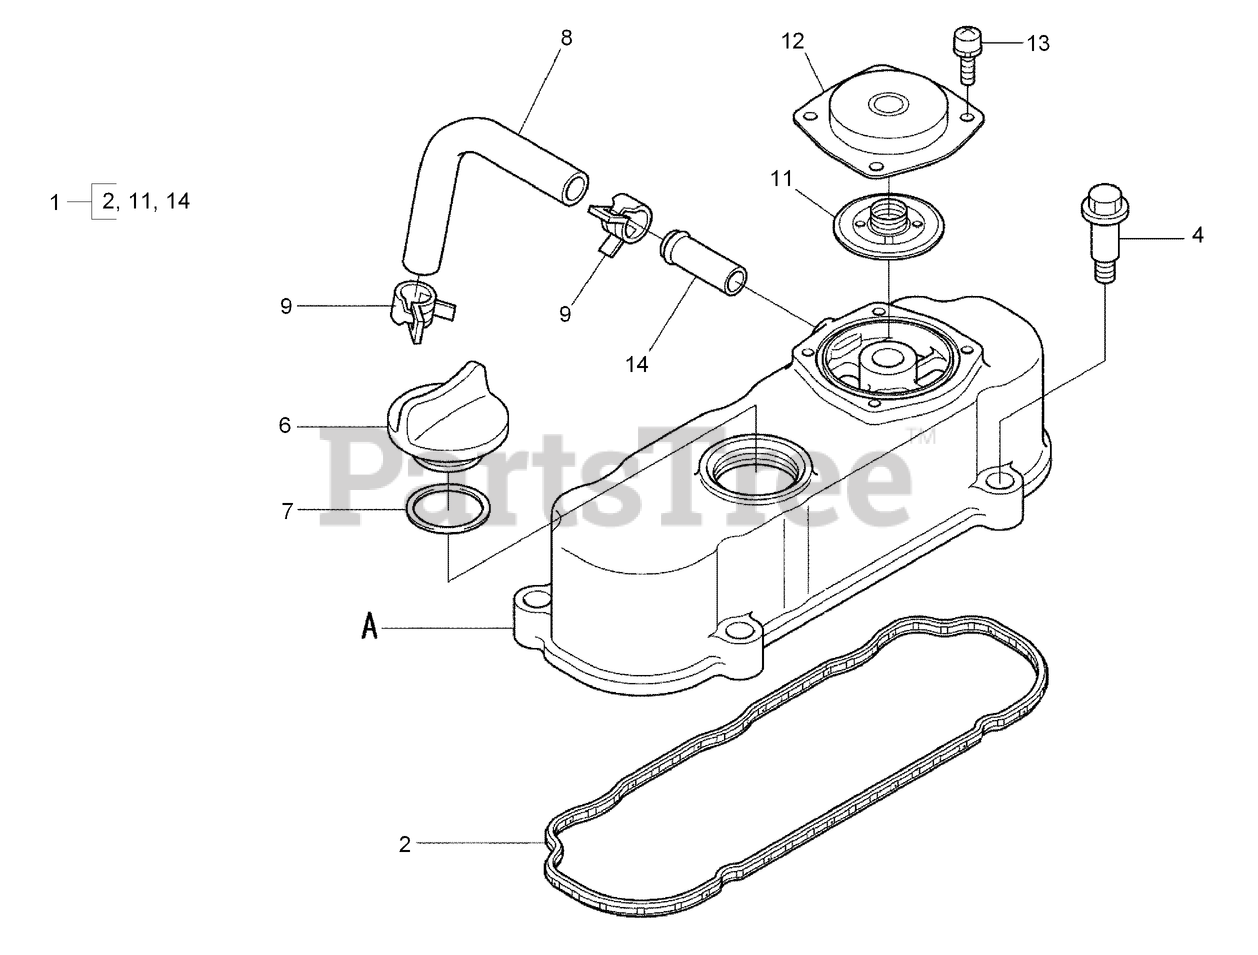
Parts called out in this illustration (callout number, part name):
1	CYLINDER HEAD COVER ASM
2	GASKET-COVER, HEAD
6	PLUG-FILLER, OIL
7	O-RING
8	TUBE-BREATHER
9	CLAMP-HOSE
11	VALVE-BREATHER
12	COVER-BREATHER
13	SCREW (WITH WASHER)
14	PIPE-RETURN, WATER
